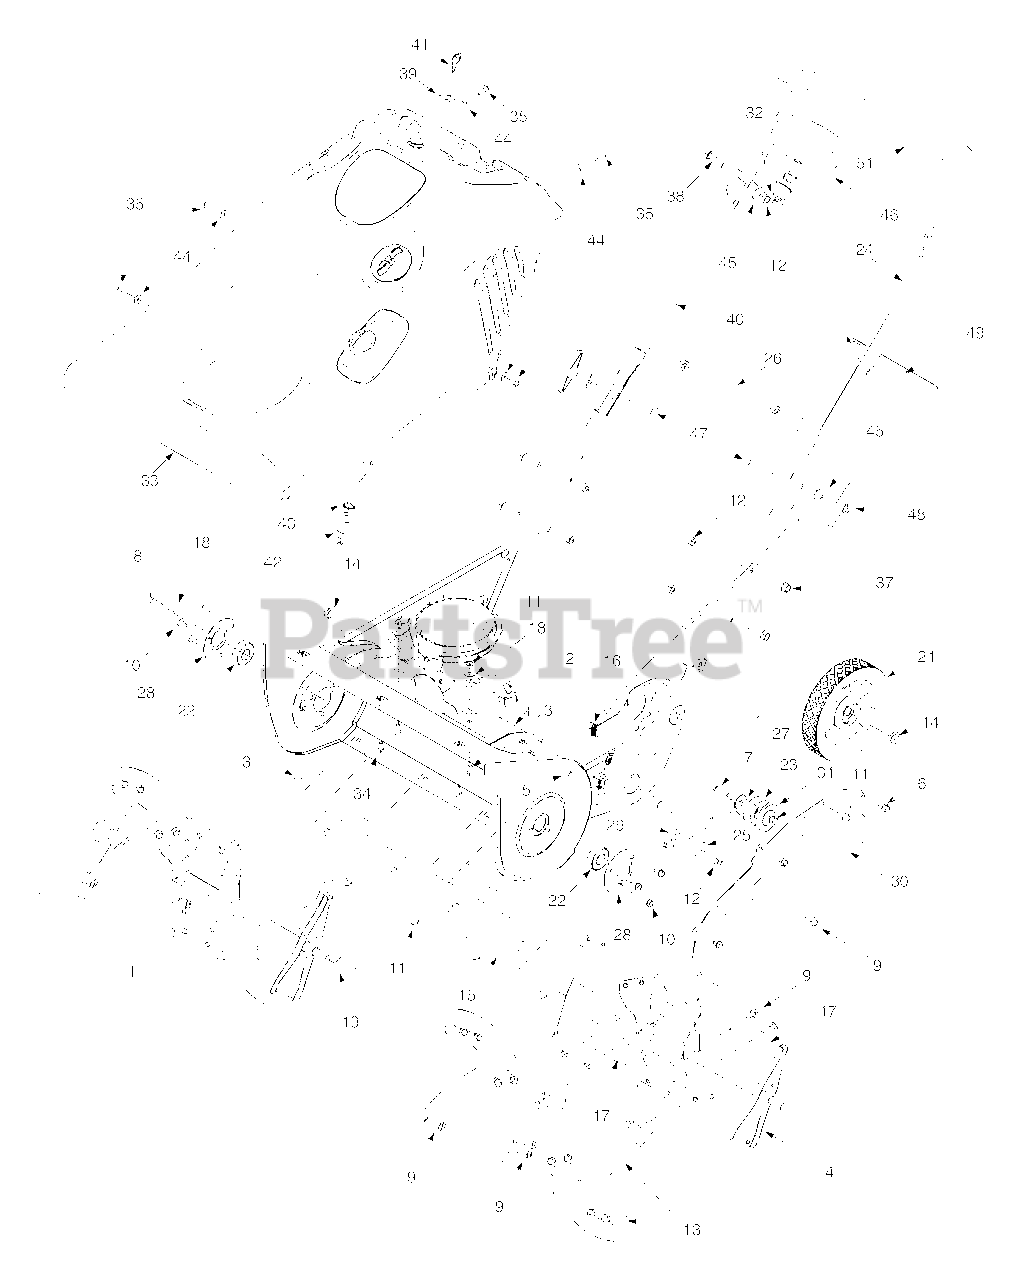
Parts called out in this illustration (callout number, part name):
1	Auger Assembly Complete
5	Truss Machine Screw, 5/16-18 x .75
6	Self-tapping Screw, 1/4-20 x .375"
7	Hex Screw, 1/4-20 x 1.00 Gr. 5
8	Self-tapping Screw, Patch 1/4-20 x .625"
9	Hex Screw, 1/4-14 x 0.625"
10	Self-tapping Screw, 1/4-14 x .50"
11	Hex Flange Lock Nut, 1/4-20
12	Hex Flange Lock Nut, 5/16-18, Gr. 5
13	Rubber Spiral Kit, w/Hdwe
14	Push Cap, 1/2"
15	Shave Plate,19.88
16	Extension Spring .33 x 1.12
17	Rubber Paddle
18	Flat Washer .265 x .938 x .120
19	Flat Washer .510 x 1.00 x .125
20	Lock Washer, 1/4
21	Wheel, 7 x 1.5 Star Gray
22	Ball Bearing 17 x 40 x 12
23	Ball Bearing
24	Control Cable
25	Shoulder Spacer .25
27	Flange Spacer
31	Belt Keeper
32	Mitten Grip Bracket
33	Shroud Assembly, Black
34	Screw, 1/4-15 x .75
35	Self-tapping Screw, #10-16 x .625"
36	Hex Flange Screw, 5/16-18x 1.25
37	Hex Flange Screw 5/16-18 x 1.50 Gr. 5
38	Hex Screw, 5/16-18 x 1.375
39	Hex Nut 5/8-32 x .12 Special
41	Ignition Key
42	Key Switch-Electric Start
43	Lock Washer Internal .625 x 1.058
44	Flat Washer .194" x .62" x .063
45	Saddle Washer .320 x .93
46	Recoil Handle, Mitten
47	Carriage Bolt 5/16-18 x 2.0 Gr. 1
48	Handle Knob Assembly 5/16-18
49	Hex Screw 5/16-24 x .75 Gr. 5
